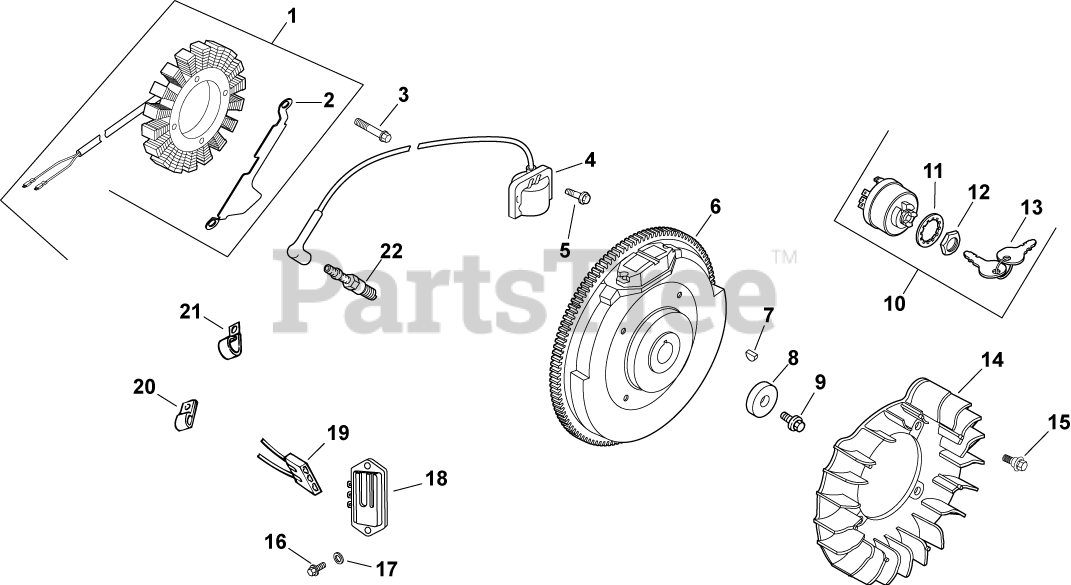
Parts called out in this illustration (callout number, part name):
1	STATOR KIT - USE 237878-S
2	BRACKET, STATOR WIRE
3	SCREW, M5X0.8X25 - (#25086402S)
4	MODULE, IGNITION-USE 24 584 45-S
5	SCREW, FLG THD FRM M5X.8X20-(#25086399S)
6	FLYWHEEL, PAINTED-USE 24 025 55-S
7	KEY, 3/16" X 5/8"
8	WASHER, FLAT 13/32"
9	SCREW, FLG M10X1.5X45 - (#25086361S)
10	SWITCH ASSY, KEY (KM)-USE 25 099 32-S
11	WASHER, INTERNAL TOOTH
12	NUT, KEY SWITCH
13	KEY, SET OF 2
14	FAN (KM)-USE 24 157 15-S
15	BOLT, SHOULDER
16	SCREW, PHL HD #11-16X7/8"
17	WASHER, FLAT 3/16"
18	REG/RECT-15 AMP (KM)-USE 41 403 10-S
19	CONNECTOR, BODY (KM)-USE 25 155 41-S
20	CLIP, TUBE & WIRING (KM)
21	CLIP, CABLE
22	PLUG, SPARK (STD)
